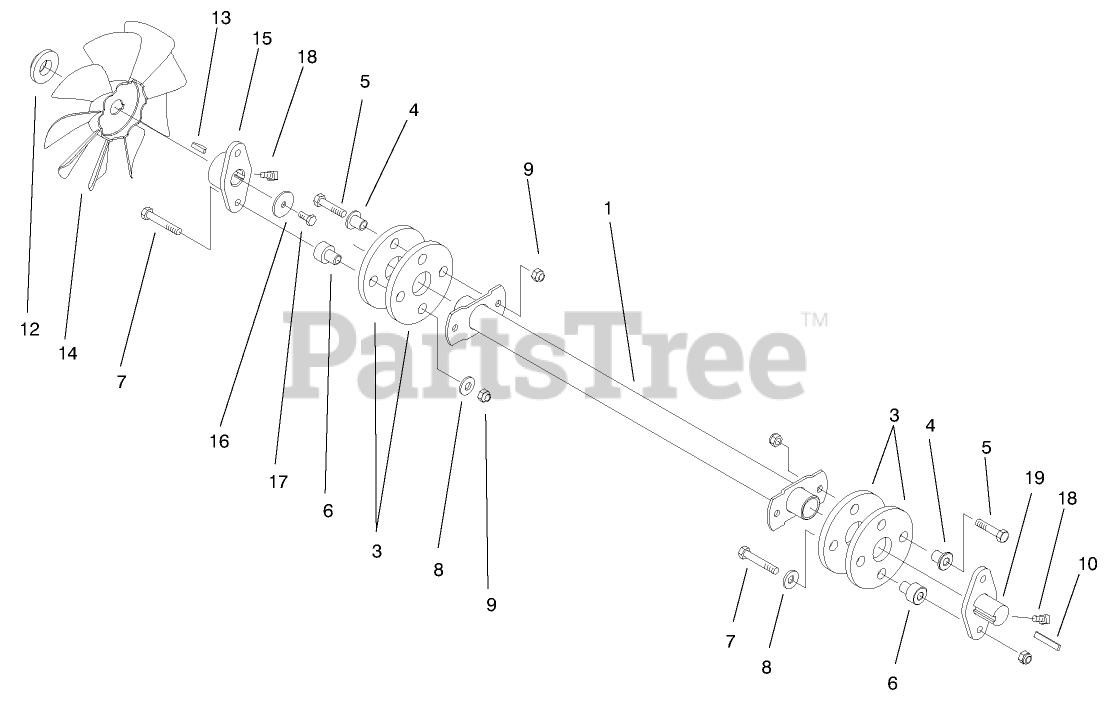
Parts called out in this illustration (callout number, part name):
1	SHAFT-DRIVE
4	SPACER
5	SCREW-HH
6	SPACER
7	SCREW-HH
8	WASHER-FLAT
9	NUT-LOCK, NI
10	KEY-SQUARE
12	SPACER-FAN
13	KEY-WOODRUFF
14	FAN-HYDRO
16	WASHER
17	SCREW-HH
18	SCREW-SET
19	WA - PIN DRIVE
